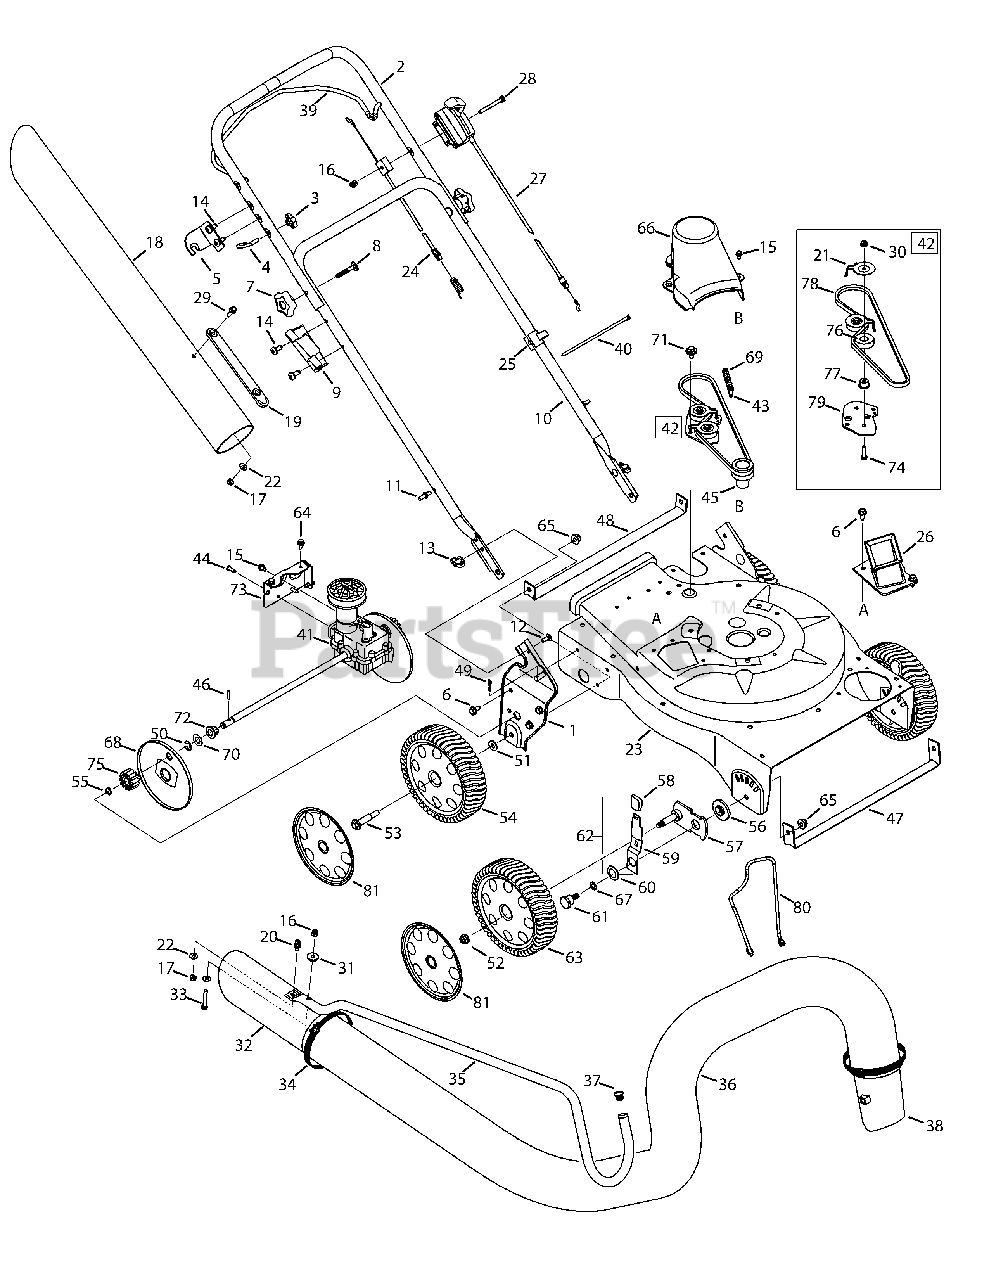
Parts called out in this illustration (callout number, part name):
1	Handle Bracket Ass’y RH
2	Upper Handle
5	Upper Handle Bracket
6	Hex Cap Screw, 5/16-12 x.750
7	Handle Knob, 5/16-18
8	Carriage Bolt
9	Nozzle Handle Clip
12	Carriage Screw, 1/4-20 x.75
13	Wing Nut, 1/4-20
14	TT Screw, 5/16-18 x .750
15	Screw, 1/4-20 x .500
16	Cap Lock Nut, 1/4-20
17	Hex Lock Nut, 1/4-20
18	Hose Extension
19	Chute Strap
21	Belt Keeper
22	Flat Washer.271 ID x.630 OD
23	Upper Flail Housing
24	Drive Control Cable
25	Cable Guide
26	Chipper Chute Assembly
27	Speed Control Cable
28	Hex Screw, 1/4-20 x 2.50
29	Screw, 1/4-20 x .75
30	Flange Lock Nut, 1/4-20
32	Hose Nozzle
33	Hex Cap Screw, 1/4-20 x 2.625
34	Adjustment Clamp
36	Vacuum Hose
37	Handle Plug
38	Hose Adapter
39	Drive Control
40	Cable Tie
41	Transmission Assembly
42	Idler Assembly (Incl. Ref.# 76-79)
43	Shoulder Screw, #12-24 x .30 x .46
44	Screw, #12-16 x .750
45	Impeller Hub
46	Dowel Pin
47	Front Wheel Support Brace
48	Rear Wheel Support Brace
49	Cotter Pin
51	Flat Washer, .406 x .875 x .105
52	Flange Lock Nut, 3/8-16
53	Shoulder Screw, 3/8-16
54	Wheel, 8 x 2
55	Snap Ring
56	Height Adjustment Bearing
57	Pivot Arm Assembly
58	Height Adjustment Knob
59	Spring Lever
60	Bell Washer, .760 ID x.25 OD
61	Shoulder Screw, .750 x.500
62	Height Lever Assembly
63	Wheel 8 x 2
64	Screw, 1/4-20 x .625
65	Flange Lock Nut, 3/8-16
66	Belt Cover
67	Thrust Washer, .375 ID x.70 OD
68	Wheel Cover
69	Extension Spring, .375 x 2.95
70	Flat Wash, .508ID x1.00OD x.020
71	Shoulder Screw, .560 x.165
72	Drive Axle Bushing
73	Transmission Mounting Bracket
74	Screw, 1/4-20 x 1.00
75	Spur Gear - RH
76	Ball Bearing
77	Flange Spacer,.260 x.659 x.517
78	Belt, 3/8 x 32.5
79	Idler Bracket
80	Tube Holder
81	Hubcap, 8"
